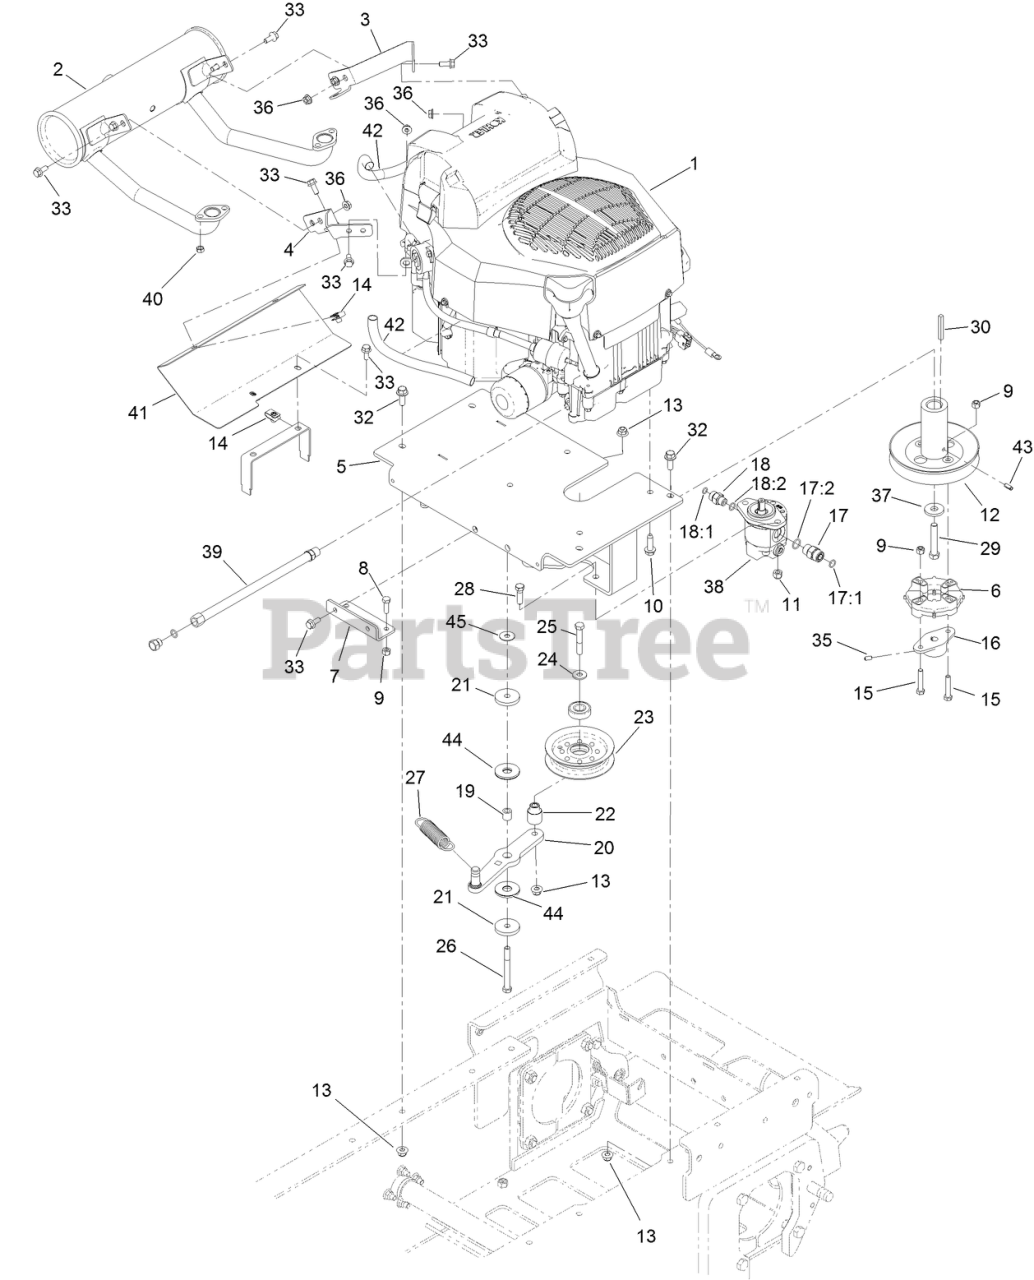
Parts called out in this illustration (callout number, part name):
1	ENGINE-KOHLER, ZT740
2	MUFFLER-KOHLER
3	BRACKET-MUFFLER
4	BRACKET-MUFFLER
5	PLATE-ENGINE
6	COUPLER-RUBBER
7	BRACKET-TANK, HYDRO
8	SCREW-HH
9	NUT-LOCK, NI
10	SCREW-THD
11	NUT-LOCK, NI
12	PULLEY-ENGINE
13	NUT-HF, NI
14	NUT-CLIP, U
15	SCREW-HH
16	HUB-PUMP
17	FITTING-STRAIGHT
17:1	O-RING
17:2	O-RING
18	FITTING-STRAIGHT
18:1	O-RING
18:2	O-RING
19	SPACER-KNOB, SEAT
20	ARM-IDLER
21	WASHER-PLAIN
22	BUSHING-IDLER
24	WASHER-HARDENED
25	SCREW-HH
26	SCREW-HH
27	SPRING-EXTENSION
28	SCREW-HH
29	SCREW-HH
32	SCREW-HHF
33	SCREW-HHF
35	SCREW-SET, HSH
36	NUT-FLANGE
37	WASHER-FLAT
38	PUMP-GEAR
39	HOSE-DRAIN, OIL
41	SHIELD-MANIFOLD
42	SLEEVE-THERMAL
43	PIN-ROLL
44	WASHER-FRICTION, COMPOSITE
45	WASHER-FLAT
